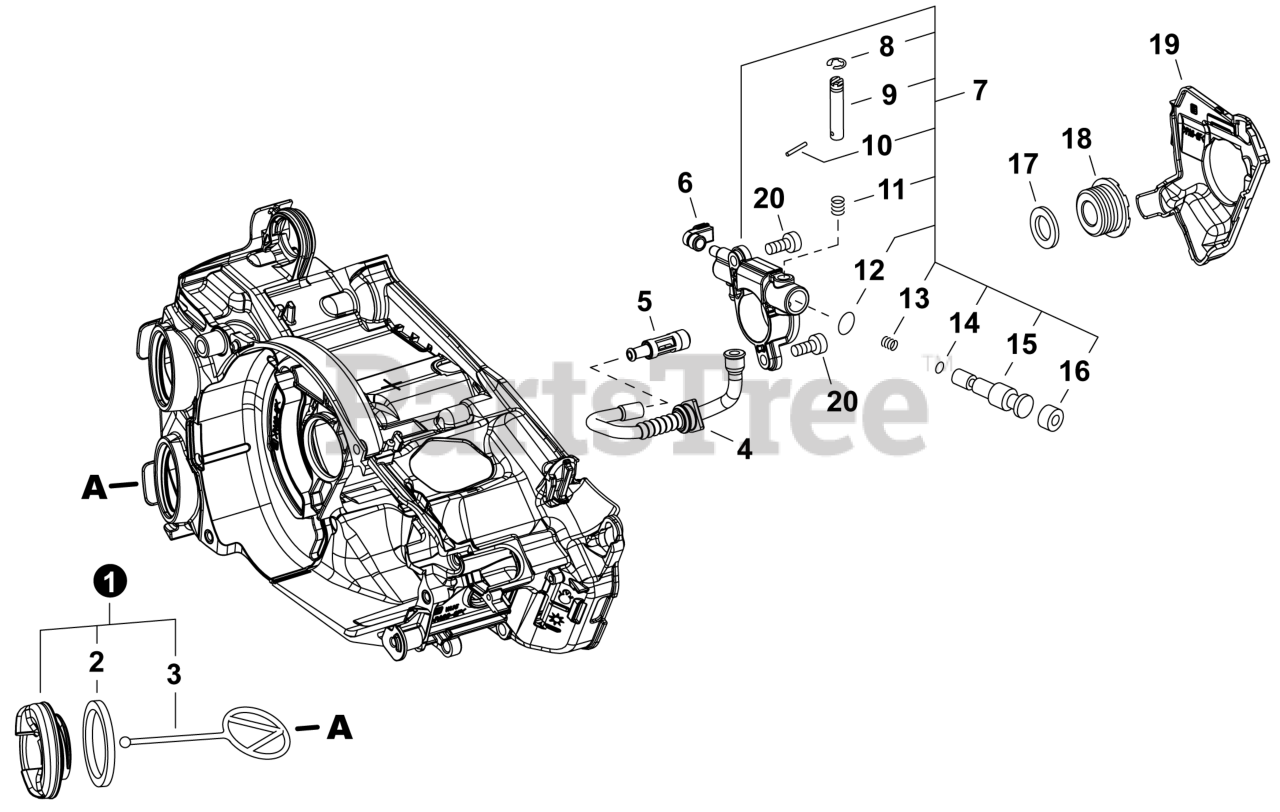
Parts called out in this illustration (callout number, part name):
1	CAP ASSY, OIL
2	GASKET, CAP
3	CONNECTOR, CAP L= 60 MM
4	PIPE, OIL
5	FILTER ASSY, OIL
6	PIPE, OIL OUTLET
7	AUTO-OILER ASSY
9	ADJUSTER, OILER
10	PIN, SPRING
15	PLUNGER ASSY
16	CAP, OIL PUMP
17	WASHER 10.5x17.4x1.8
18	GEAR, WORM
19	COVER, OILER
20	BOLT, TORX 4x12
